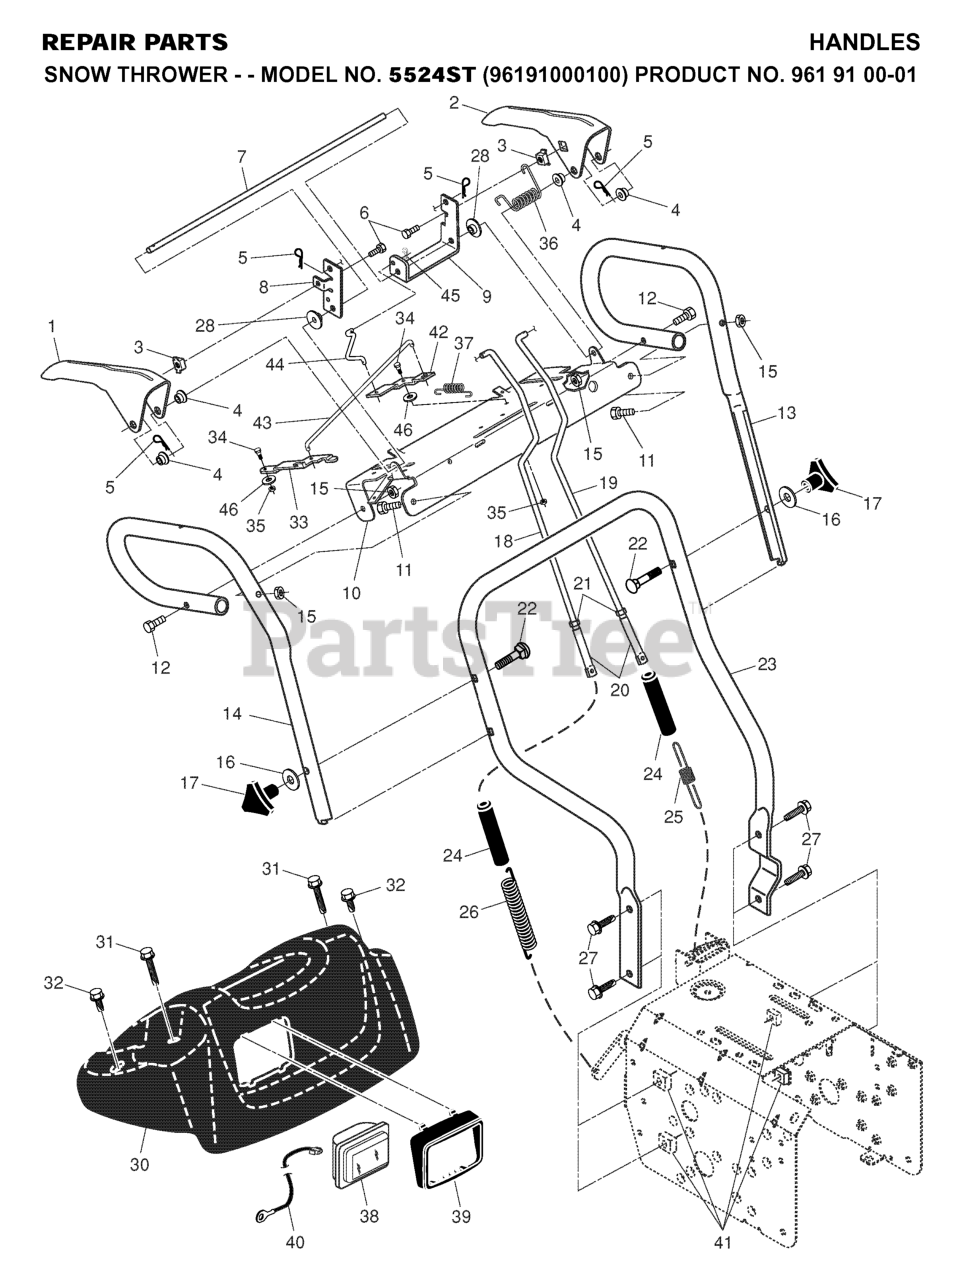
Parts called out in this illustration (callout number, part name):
1	LEVER, AUGER CONTROL
2	LEVER, TRACTION DRIVE CONTROL
3	NUT, CAGE 1/4-20
4	BUSHING, FLANGE
5	SPRING RETAINER
6	SCREW HEX HD 1/4-20 X 3/4
7	ROD.INTERLOCK
8	ARM,IMPELLER ROD
9	ARM,TRACTION ROD
10	PANEL.CONTROL
11	HEX BOLT
13	HANDLE TUBE LH
14	HANDLE TUBE RH
15	NUT.71038.31-18.HEX.NYLOCK
16	WASHER
17	KNOB.HANDLE.3/8.TRI-POINT.BLAC
18	ROD.AUGER.CONTROL
19	ROD.CABLE.TRACTION.LONG
20	ROD, END CONTROL
21	JAM NUT TI
22	BOLT 3/8-16 X 2-1/4
23	TUBE.LOWER.HANDLE.24.BLACK
24	SLEEVE, SPRING
25	SPRING, TRACTION DRIVE
26	SPRING, AUGER CONTROL
27	Capscrew, Hex Head, Flanged 3/8-16 x 1
28	RP BUSHING, IDLER PIVOT
30	PANEL.CONSOLE.HEADLIGHTS
31	SCREW, HEX HD TAPPING #10-24 1
32	SCREW, HEX HEAD, TAPPING
33	LATCH.INTERLOCK
34	BOLT, SHOULDER
35	NUT **
36	RP SPRING, TORSION
37	SPRING LATCH
38	HEADLIGHT.HALOGEN.SNOW
39	BEZEL.HEADLIGHT.BLACK
40	HARNESS.WIRE.HALOGEN
41	NUT, CAGE 3/8-16
42	LEVER.INTERLOCK
43	ROD.LATCH.INTERLOCK
44	ROD.ASM INTERLOCK
45	RETAINER CLIP
46	WASHER, NYLON FRICTION
